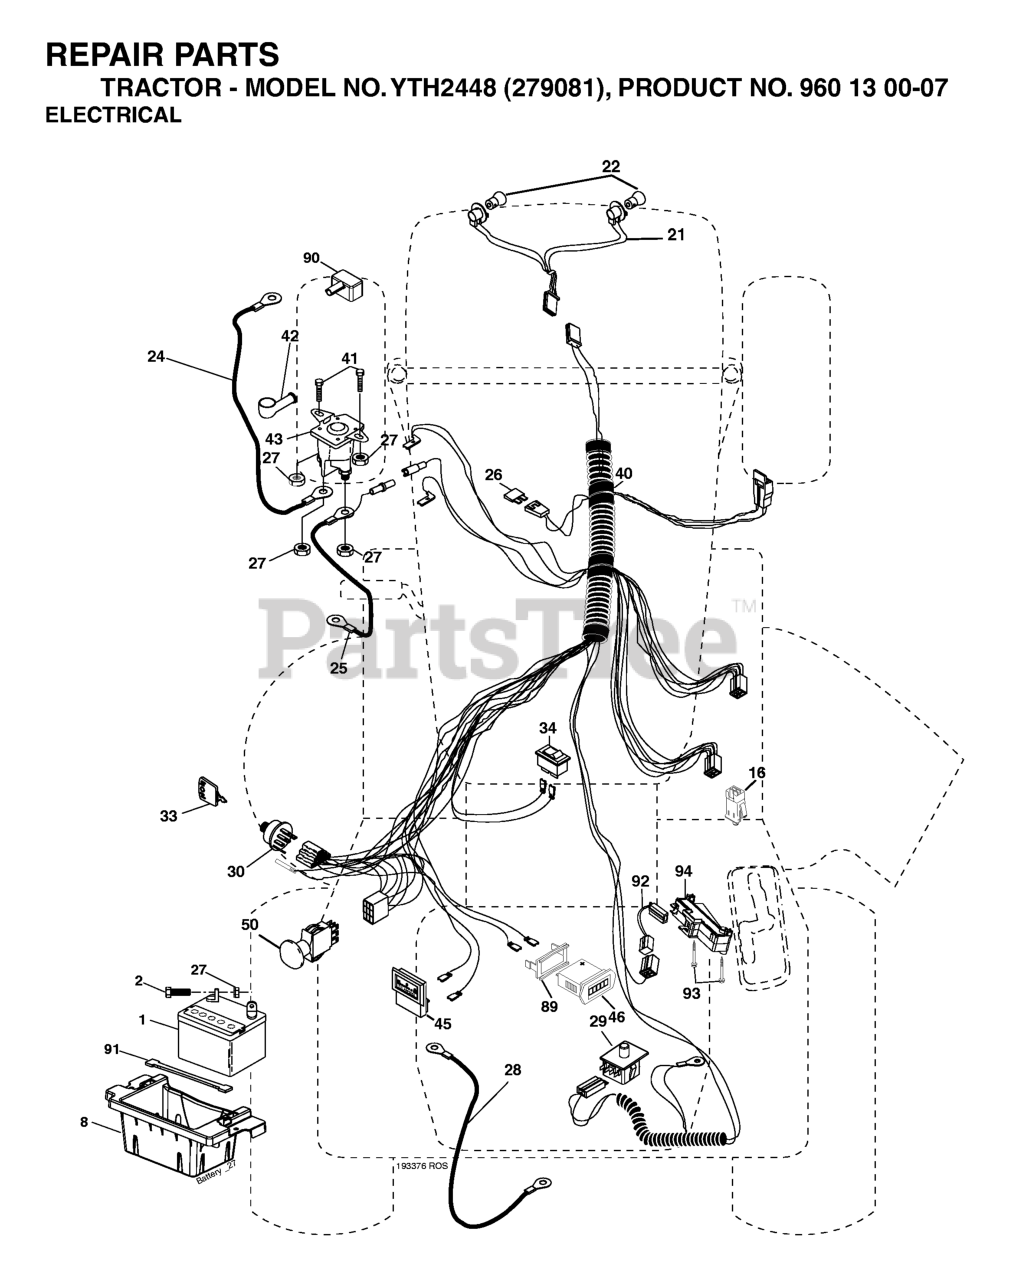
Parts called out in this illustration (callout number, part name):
1	BATTERY 12V .35 AMP
2	BOLT.HEX.1/4.X.3/4.DICHROMATE
8	BOX.BATTERY.MOUNT.FRONT.LT
16	SWITCH INTERLOOK PUSH-IN
21	HARNESS ASSY LIGHT
24	BATTERY CABLE GT
25	CABLE BATTERY 6 GA 22" W/16W
26	FUSE 20AMP
27	NUT
28	CABLE GROUND 6 GA 21" 90T BLK
29	SWITCH.SEAT.DP W/RAMPS
30	SWITCH.IGN.DELTA.W.LGH.ROS
33	KEY MLD GEN DELTA
40	HARNESS.IGN.ELECT.STL
41	SCREW
42	TERMINAL COVER
43	SOLENOID
46	HOUR METER
50	RP.SWTICH.PTO.8.TERMINAL
89	BRACKET SNAP-IN HOURMETER
90	COVER TERMINAL
91	STRAP.BATTERY.MOUNT.FRONT(2 2)
92	HARNESS.PIGTAIL.REVERSE.SWITCH
93	SCREW.PLASTITE
